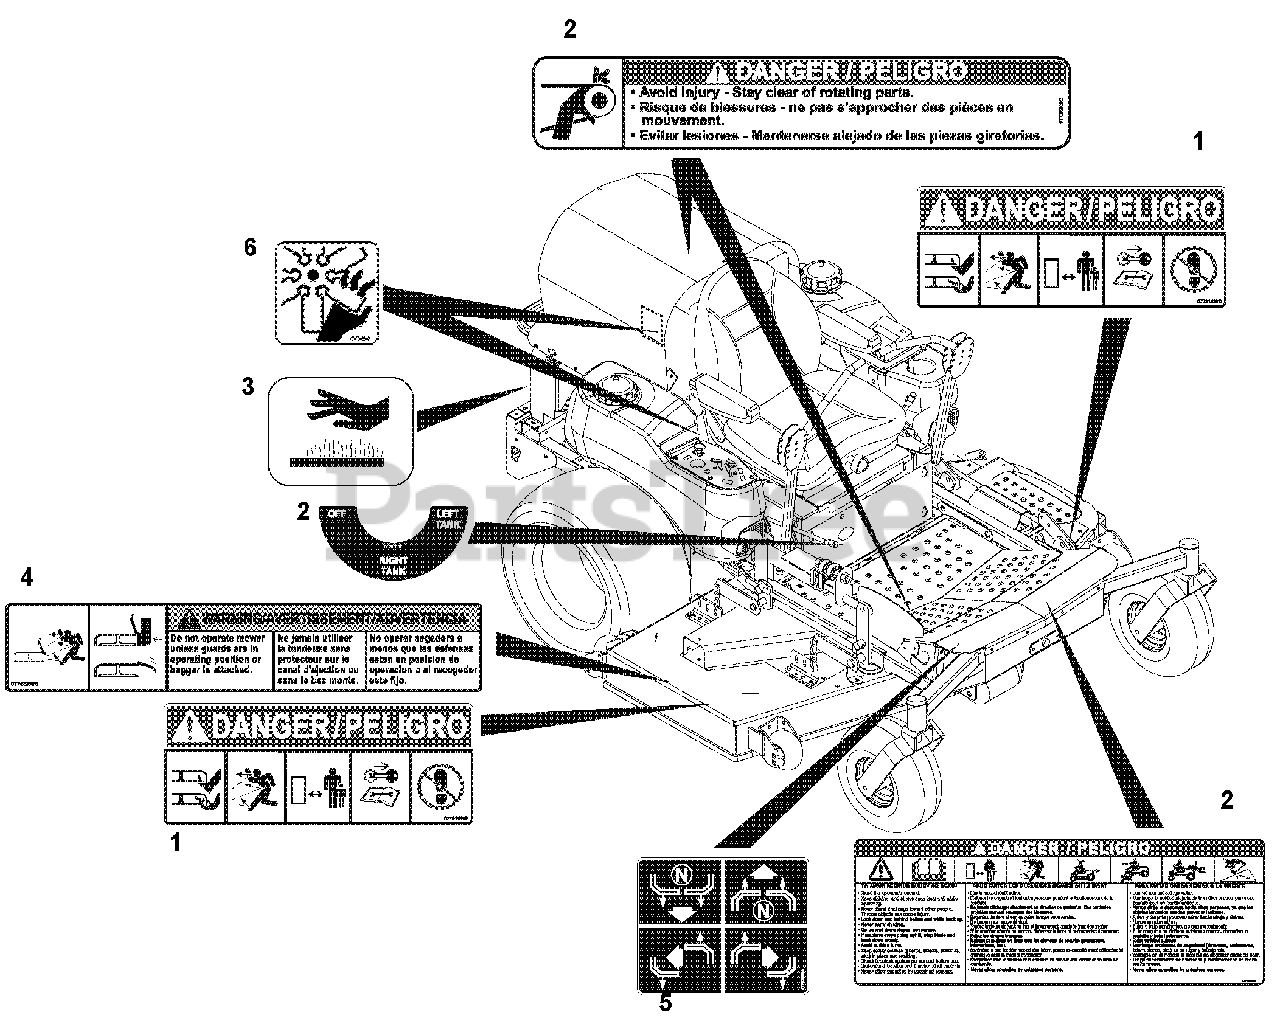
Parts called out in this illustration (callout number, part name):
1	Decal, Mower Pan Head Danger
2	Set, Decal-Common Danger/Fuel
3	Decal-Hot Surface
4	Decal, Warning
5	Decal-Instructional
6	Decal, Danger Fan
